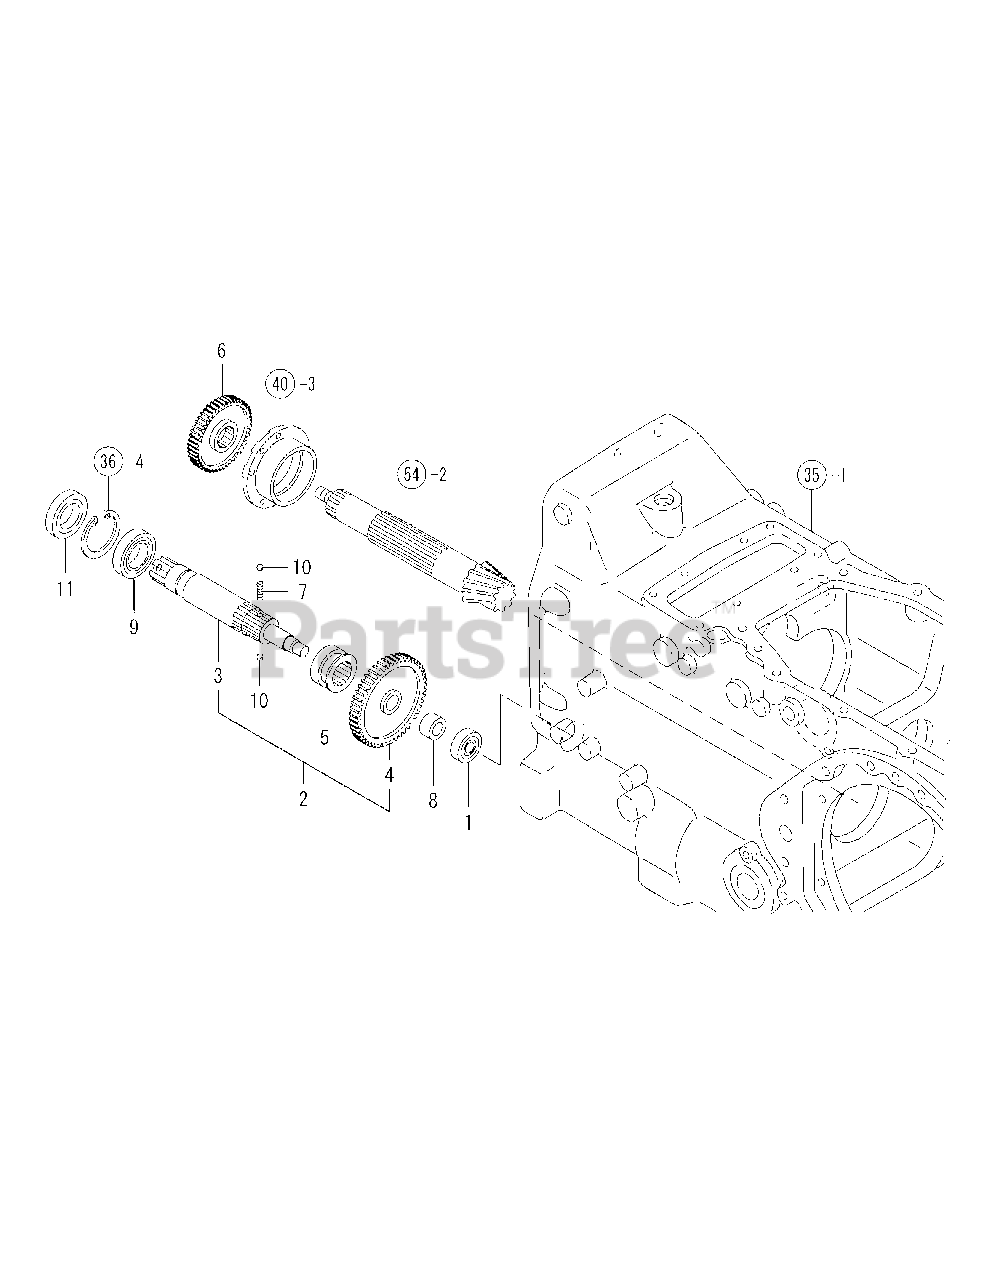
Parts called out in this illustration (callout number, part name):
2	GEAR KIT,DRIVE
3	SHAFT, FRONT DRIVE
4	GEAR,FRONT DRIVE
6	GEAR, FRONT DRIVE
9	BALL BEARING #6007
10	BALL 1/4, STEEL
11	SEAL TC35 62 12, OIL
